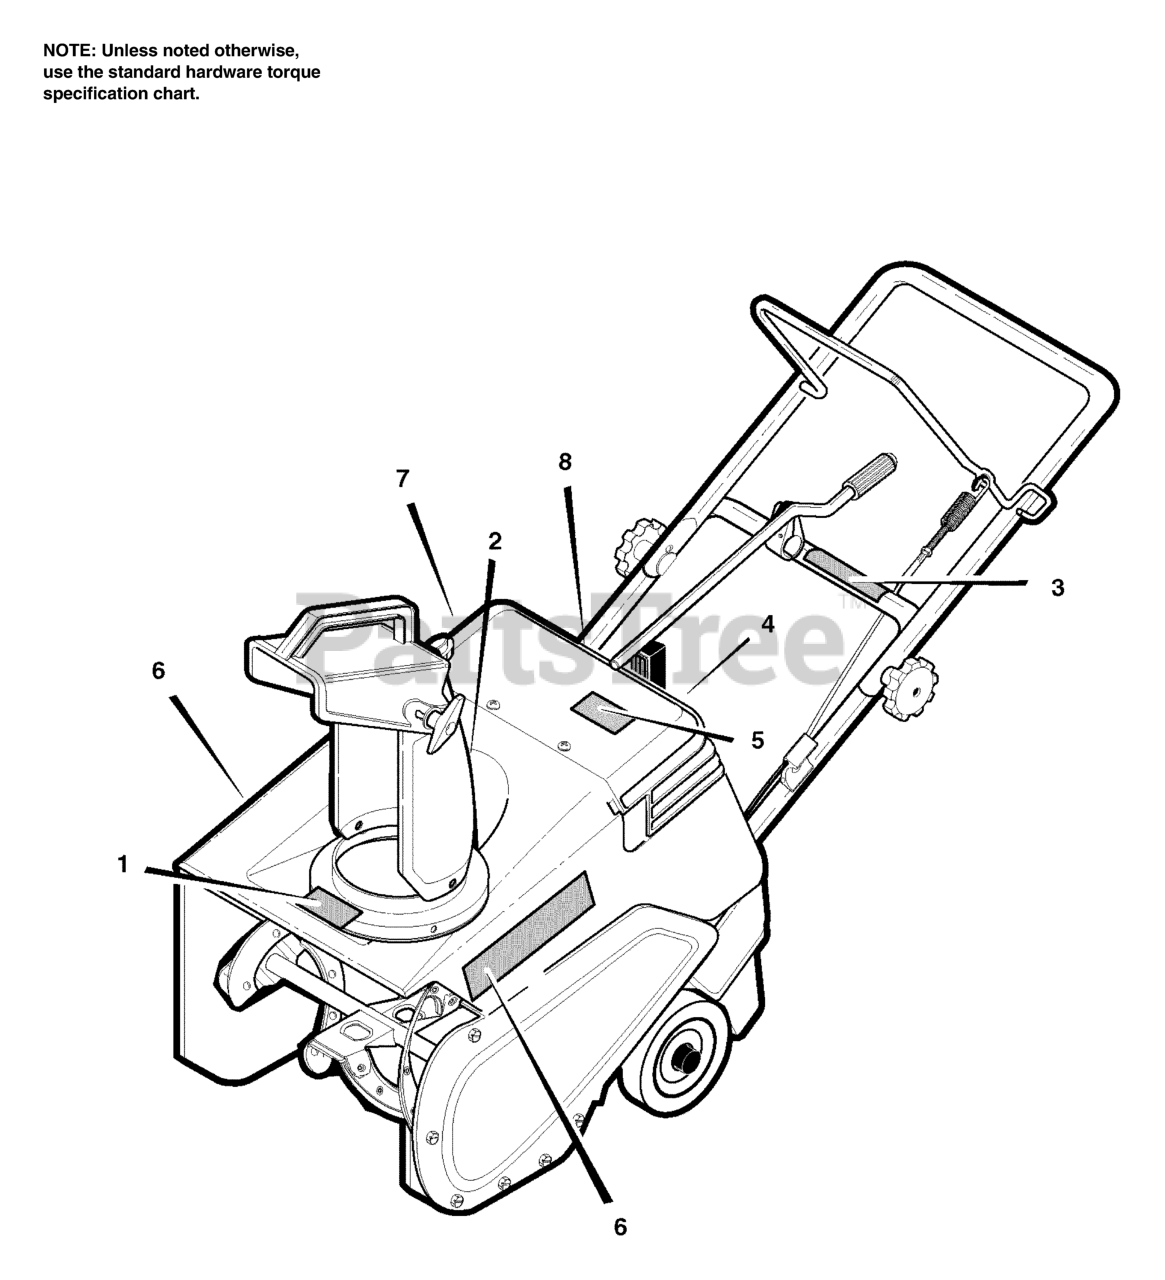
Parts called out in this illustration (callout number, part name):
1	DECAL, DANGER AUGER
2	DECAL, DANGER CHUTE
3	DECAL, AUGER CONTROL BAR
4	DEC-CTRL PANEL ELEC S
4	DEC-CTRL PANEL RECOIL
5	DECAL, WARN HOT MUFL
6	DECAL, HUSQVARNA
7	DECAL, EPA
8	DECAL, 521SSE
8	DECAL, 521SSR
